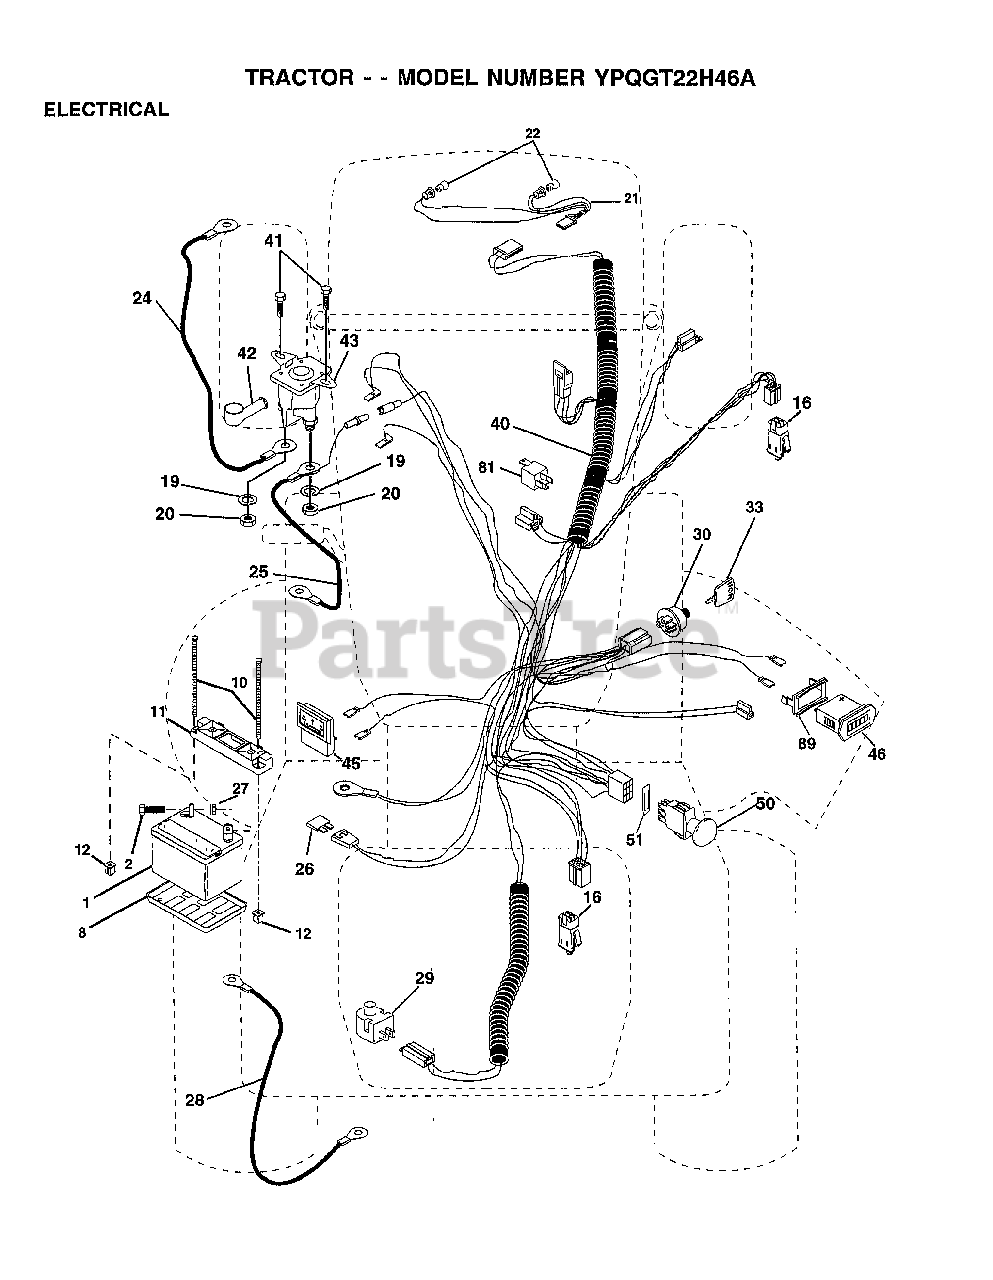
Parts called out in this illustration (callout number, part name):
2	BOLT LT
8	"TRAY T, BATTERY"
11	HOLDDOWN BATTERY
16	SWITCH INTERLOCK
20	NUT
21	HARNESS.ASM.LIGHT.W/4152J
22	HEADLAMP BULB
24	CABLE.BATY.22.RED
25	CABLE.BATRY.4GA.
26	FUSE HYT
27	NUT
28	"CABLE BATTERY,GRD"
29	SWITCH.PLUNGER
30	SWITCH.IGN.
33	KEY MLD GEN DELTA
40	HARNESS.IGN.
41	SCREW
45	AMMETER
46	METER HOUR
50	PTO SWITCH.BLK
51	RING RETAIN PTO
81	RELAY ASSY T
89	BRACKET SNAP
